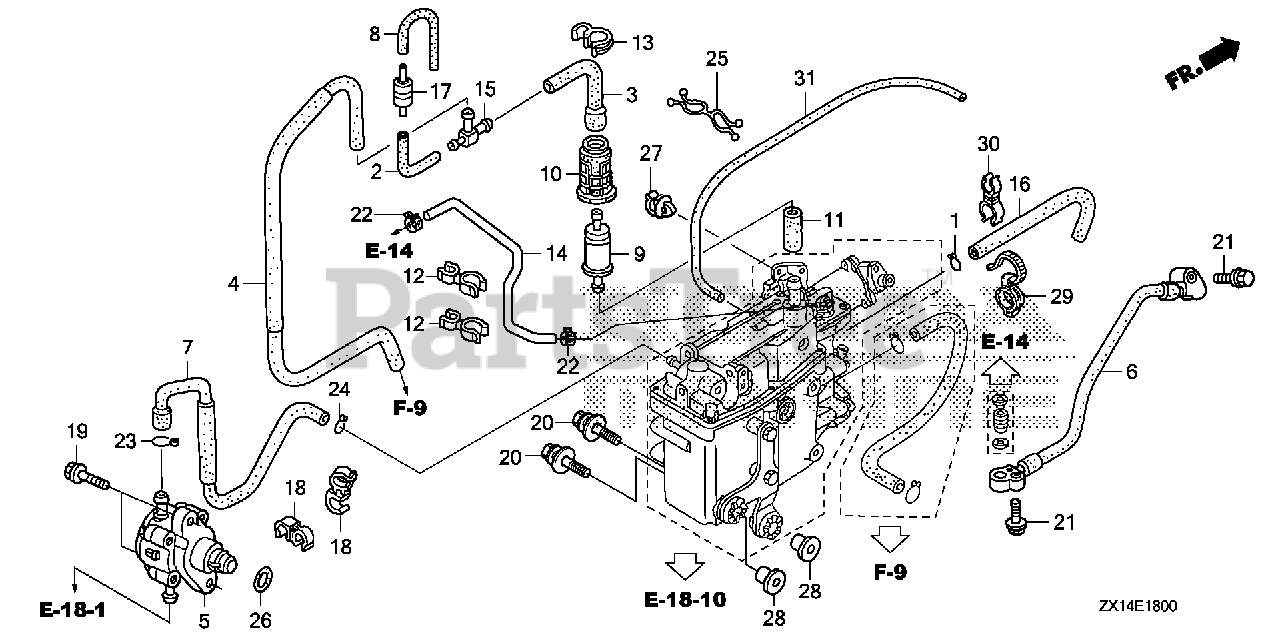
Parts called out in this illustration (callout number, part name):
1	CLIP, TUBE
2	TUBE C, AIR VENT
3	TUBE B, AIR VENT
4	TUBE, AIR VENT
5	PUMP ASSY., FUEL (MSDS)
6	HOSE, FUEL
7	TUBE B, FUEL
8	TUBE D, FUEL
9	FILTER, FUEL PUMP
10	SUSPENSION, STRAINER
11	TUBE B, FUEL
12	CLAMP, HOSE
13	CLAMP, PIPE
14	HOSE, PRESSURE REGULATOR RETURN
16	TUBE G, WATER
17	VALVE, CHECK
18	CLIP, SENSOR HOSE
19	BOLT, FLANGE (6X27)
20	BOLT-WASHER (8X35)
21	BOLT, FLANGE (6X25)
22	CLAMP, TUBE (D10.7)
23	CLIP, TUBE (B1 14.5)
24	CLIP, TUBE (B12)
25	CLIP, FUEL HOSE
26	O-RING (33.2X2.4) (NOK)
27	CLIP, HARNESS
28	COLLAR (8.5X14.5)
29	CLIP, TUBE (135MM) (BLACK)
30	CLAMP, PURGE HOSE (NOT AVAILABLE)
31	BULK HOSE, FUEL (3.5X3000) (3.5X430)
